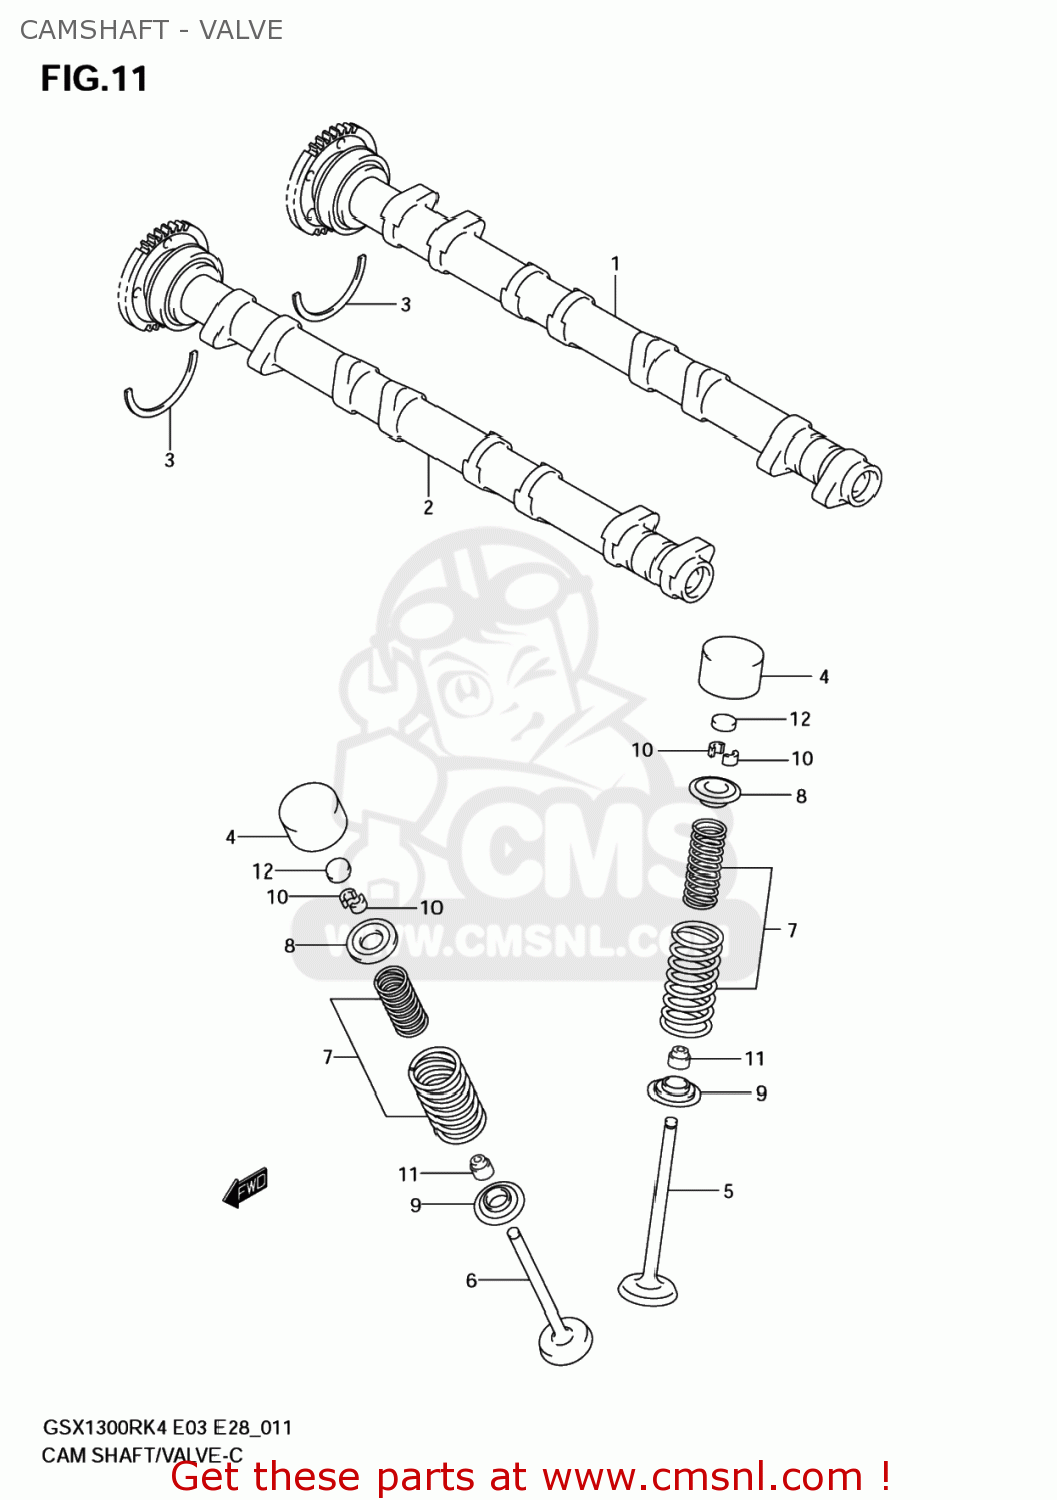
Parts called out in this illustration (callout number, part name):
1	CAMSHAFT,INTAKE
2	CAMSHAFT,EXHAUST
3	C RING
4	TAPPET
5	VALVE,INTAKE
6	VALVE,EXHAUST
7	SPRING SET,VALVE
8	RETAINER,VALVE SPRING
9	SEAT,VALVE SPRING
10	COTTER VALVE
11	SEAL,OIL(5X10X9.7)
12	SHIM,TAPPET(T:2.3)
13	SHIM SET,TAPPET
14	CASE,TAPPET SHIM
